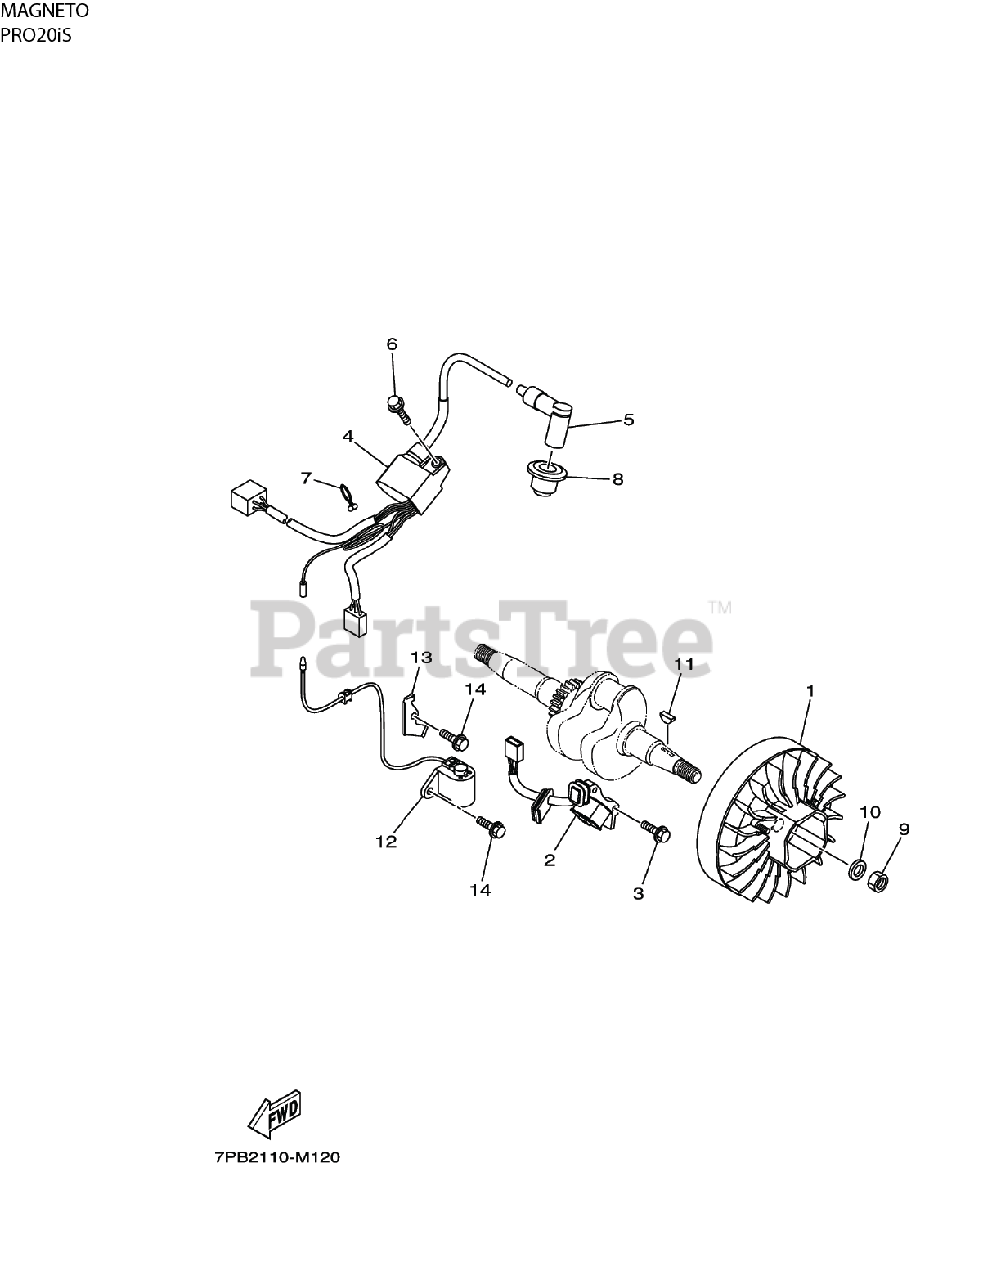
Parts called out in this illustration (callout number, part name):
1	FLYWHEEL, ROTOR ASSEMBLY
2	TRIGGER ASSEMBLY - COIL ASSEMBLY
3	SCREW - BOLT
4	COIL, IGNITION ASSEMBLY
5	CAP, PLUG ASSEMBLY
6	SCREW - BOLT
7	CLIP, CLAMP
8	SEAL, PLUG CAP
10	COIL, IGNITION ASSEMBLY
11	KEY, WOODRUFF
12	SWITCH, OIL LEVEL GAUGE ASSEMBLY
13	BRACKET, LEAD
14	SCREW - BOLT FLANGE
